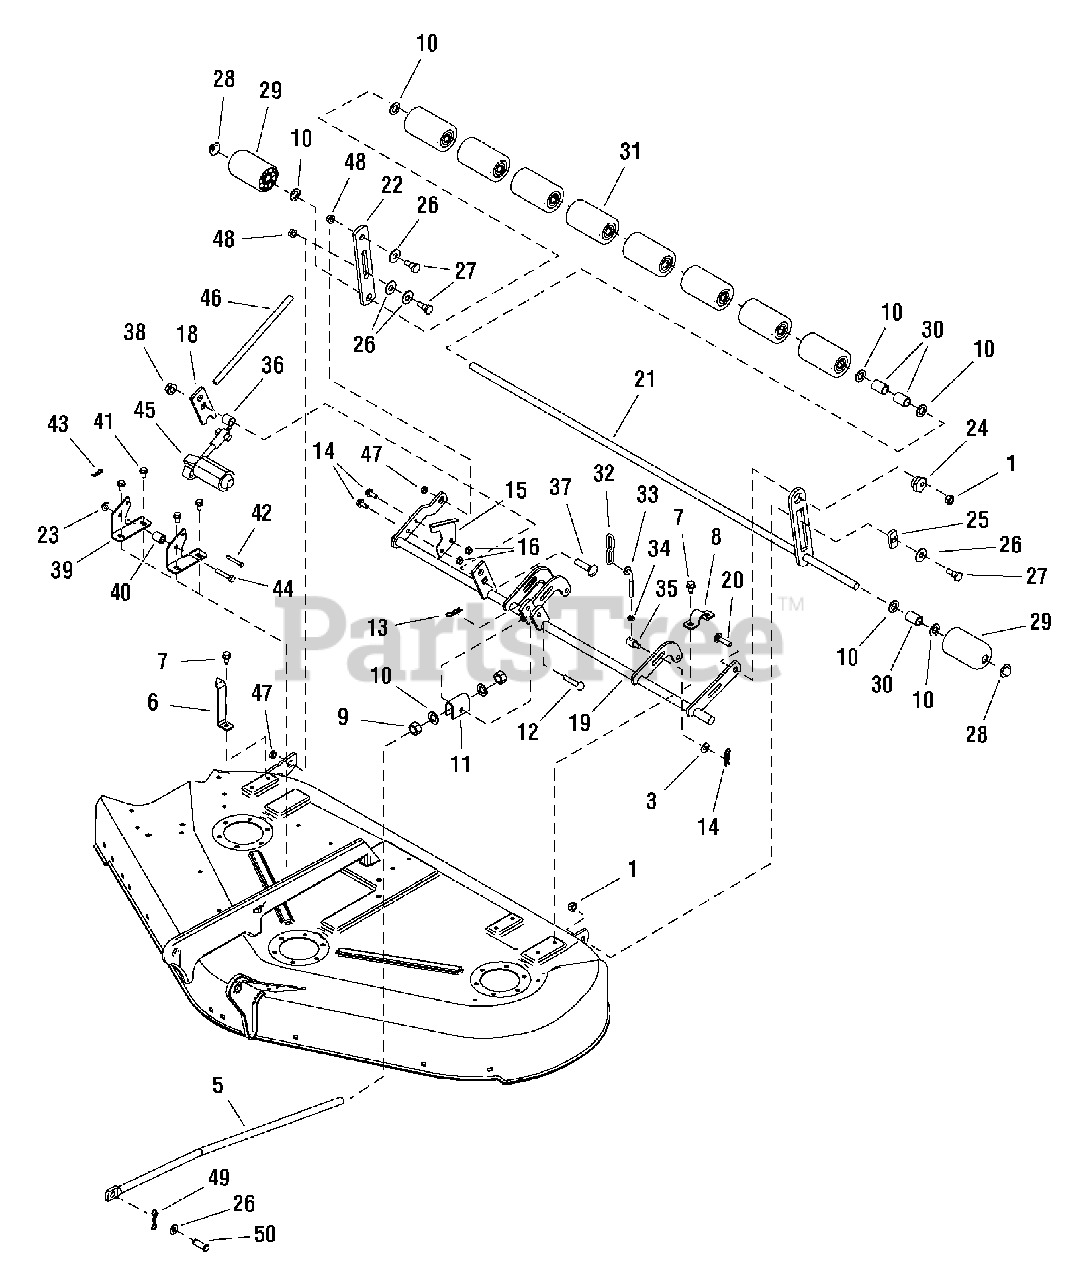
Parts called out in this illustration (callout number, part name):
1	NUT, Hex TopLock Spiral Lock Flange 3/8-16
3	WASHER, 3/8
5	ROD, Adjusting
6	INDICATOR, Height of Cut
7	SCREW, Hex Washer Head Taptite 5/16-18 x 3/4
8	STRAP
9	NUT, Hex 5/8-11
10	WASHER, 5/8
11	TRUNNION
12	PIN, Round Head Drilled 3/8 x 2
13	CLIP, Hair Pin
14	SCREW, Hex Whiz Lock Flange 5/16-18 x 3/4
15	BRACKET, Height of Cut 16GA
16	NUT, Hex Flange 5/16-18 Whiz Lock Small
18	ARM, Rear
19	SHAFT ASSEMBLY, Rocker 50"
20	CARRIAGE BOLT, 3/8-16 x 1-1/2 G5
21	SHAFT & BAR ASSEMBLY, Roller
22	BAR, Roller
23	NUT, Hex Flange 5/16-18 Whiz Lock Large
24	NUT, Hex Adjusting, .99 DIA .687
26	WASHER, 1/2
27	BOLT, Shoulder, 3/8-16 X 1.34
28	NUT, Push for 5/8 Diameter Stud Capped
32	CHAIN, Link
33	ROD, Height Adjusting
34	NUT, Hex Jam 5/16-18
36	SPACER, .66 ID
37	CARRIAGE BOLT, 1/2-13 x 2 G5
38	NUT, Hex Toplock Flange 1/2-13
39	BRACKET, Mounting
41	SCREW, Hex Washer Head Taptite 5/16-18 x 5/8
42	PIN, Shear
43	CLIP, Hairpin
44	CAPSCREW, Hex Head 5/16-18 x 1-3/4 G5
45	MOTOR, Electric
48	NUT, Hex Flange 3/8-16 Machine Lock Large
49	PIN, Locking
50	PIN, Clevis 1/2
